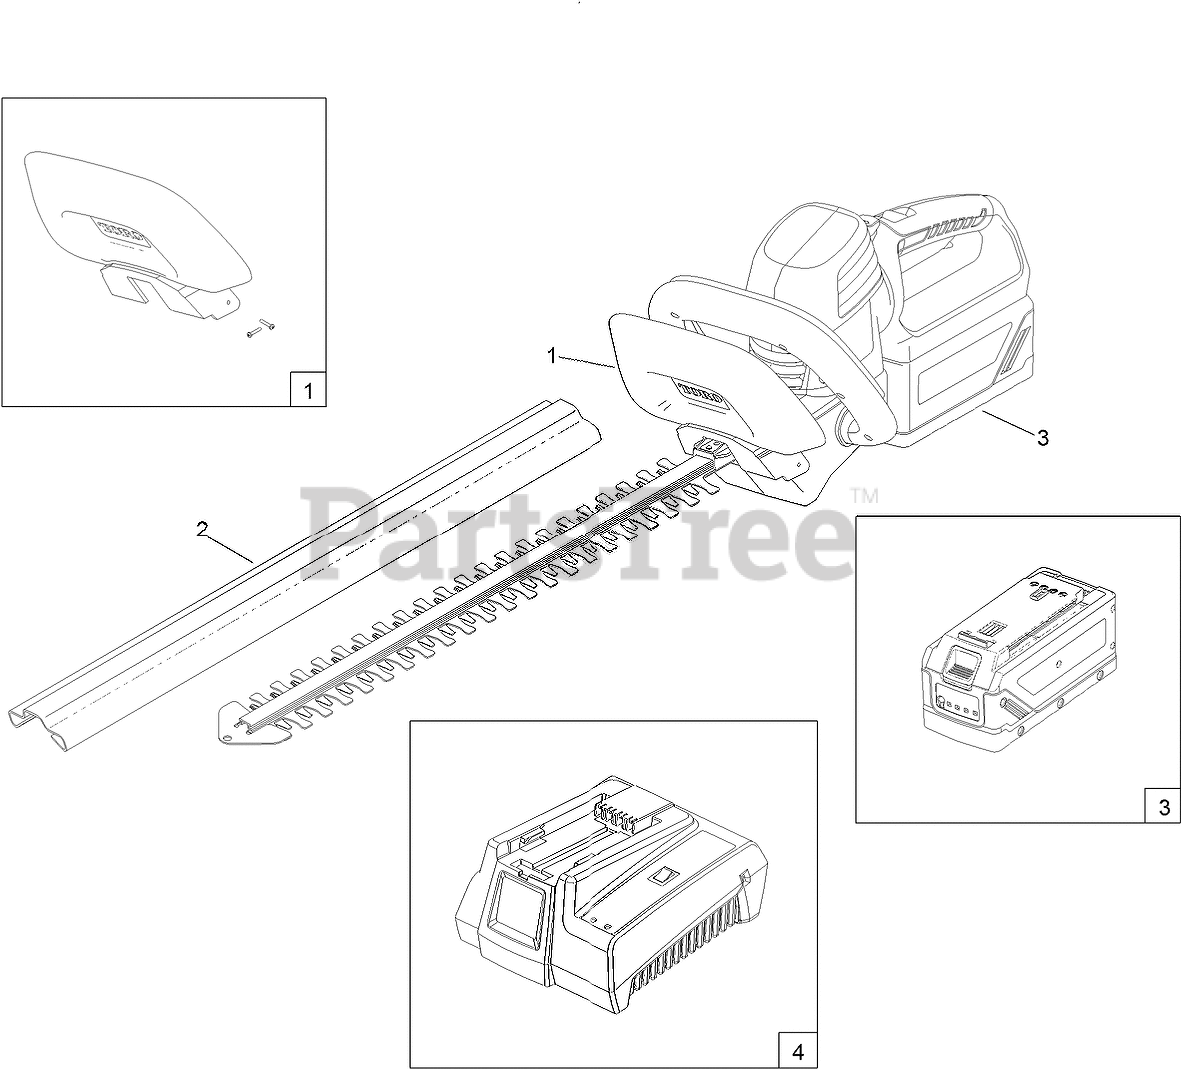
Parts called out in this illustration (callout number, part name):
1	GUARD ASM
2	SHEATH-BLADE
3	BATTERY-48V (2AH)
4	CHARGER-48V
